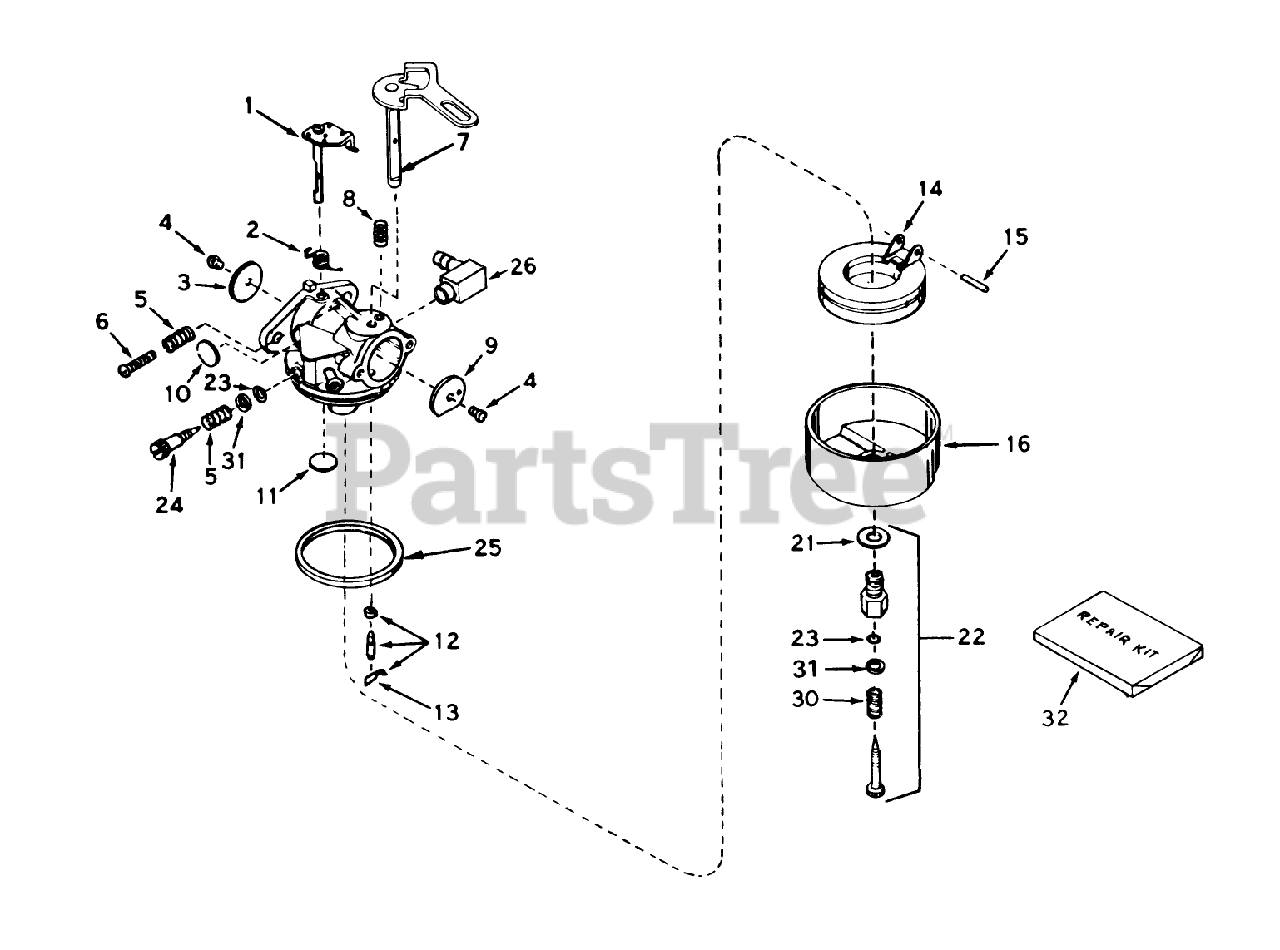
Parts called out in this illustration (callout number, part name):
1	Throttle Shaft and Lever ASM
2	Spring-Return, Throttle
3	Shutter-Throttle
4	Screw-Shutter
5	Spring-Tension
6	Screw-Throttle Crack Screw / Idle Speed
7	Choke Shaft and Lever Asm
8	Spring-Positioning, Choke
9	Shutter-choke
10	Plug-Welch, Idle Mixture Well
11	Plug-Welch, Atmospheric Vent
12	Inlet Needle, Seat Clip Assy. (Incl. No. 13)
13	Clip-Spring
14	Float
15	Shaft-Float
16	Bowl-Float (no drain)
21	Washer-Bowl Nut
22	Adjustment Screw Assy., Main (Incl. Nos. 5A, 21 23)
23	ORing
24	Screw, Idle Adj.
25	O Ring-Bowl, Float
26	Fitting-Fuel
30	Spring
31	Washer
32	Repair Kit (Incl. items marked *)
